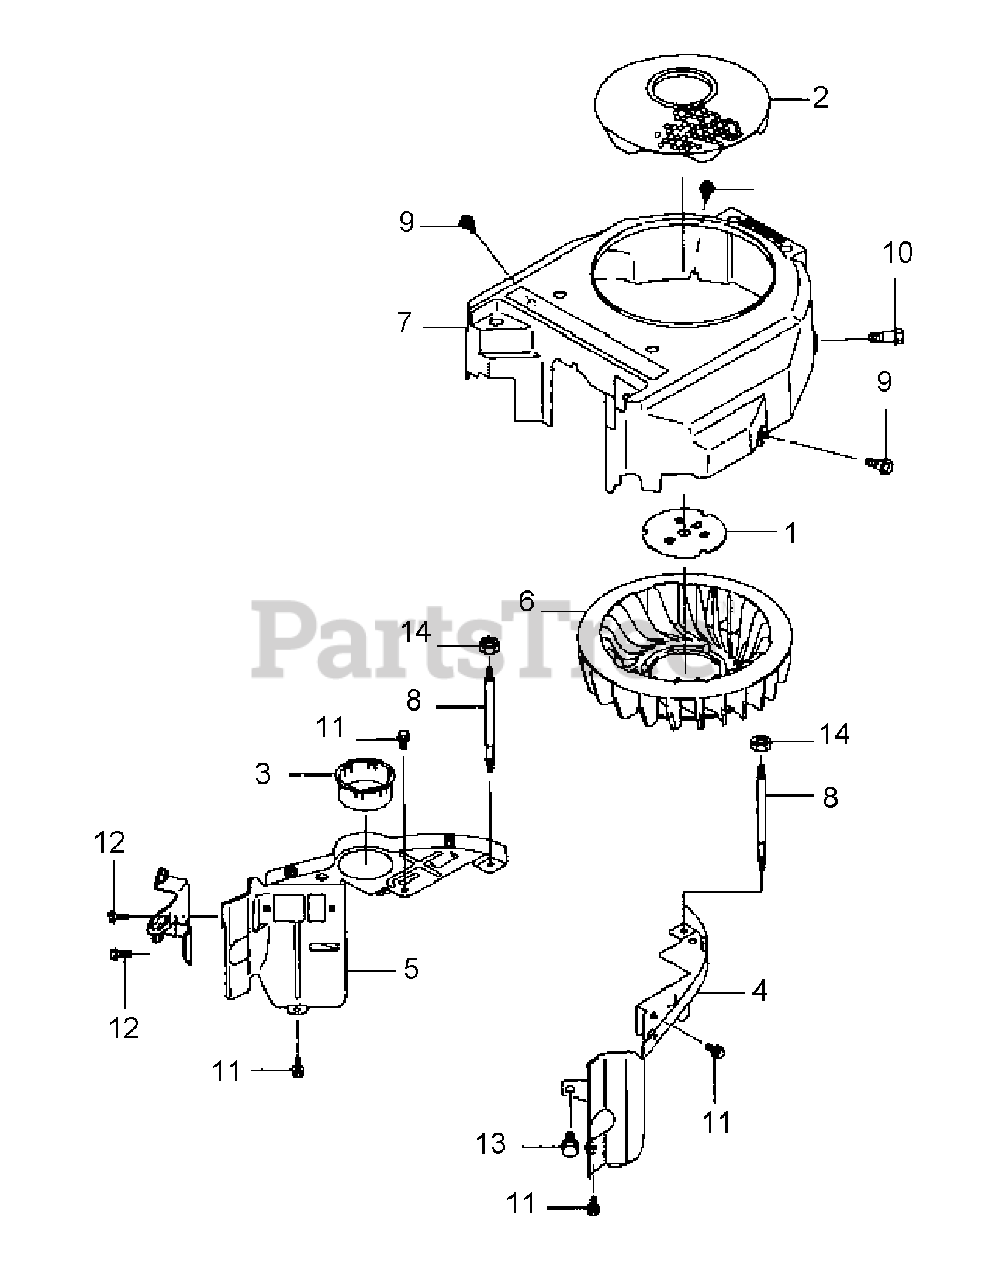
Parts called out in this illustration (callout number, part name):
4	ENGINE SHROUD
5	ENGINE SHROUD
6	FAN
10	BOLT
11	FLANGED BOLT
12	FLANGED BOLT
13	FLANGED BOLT
